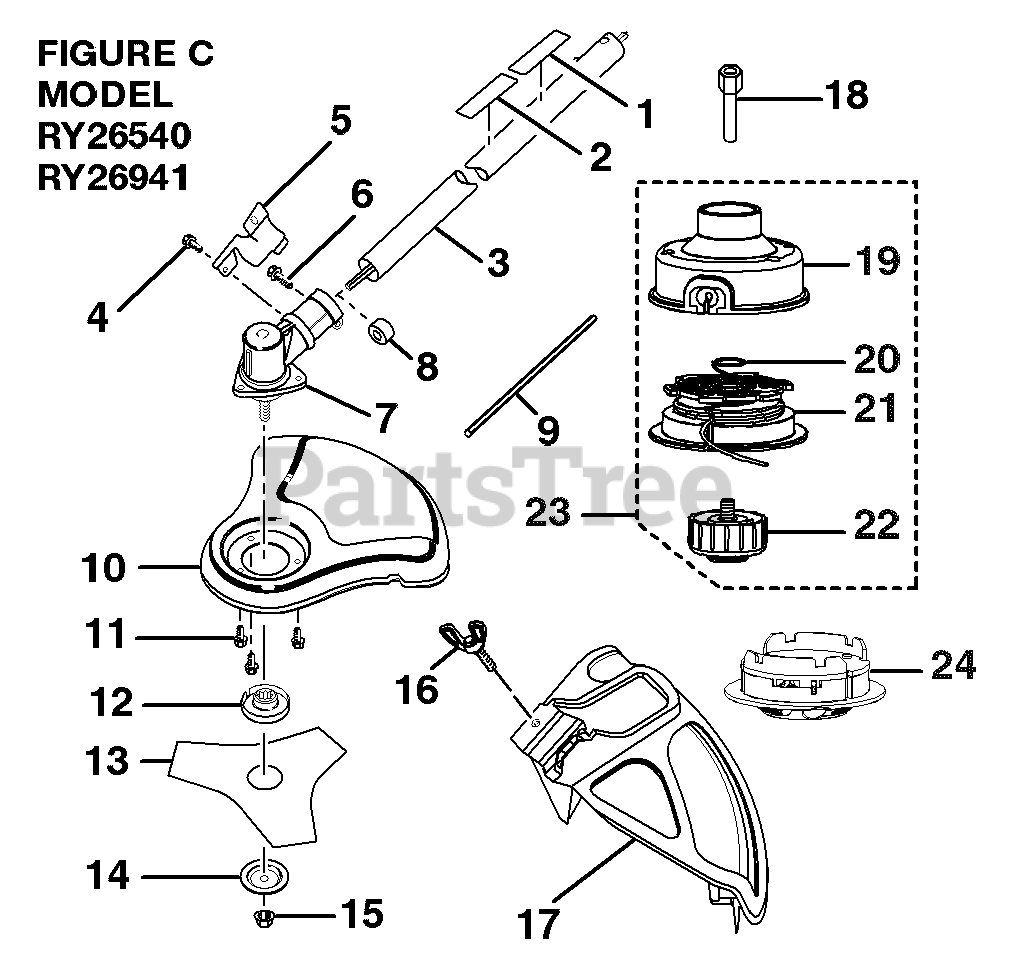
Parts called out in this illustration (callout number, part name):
1	Expand-it Label
2	Brushcutter Safety Label
3	Straight Shaft Assembly
4	Screw (10-24 x 5/8 in.)
5	Clamp
6	Screw (1/4-20 x 1-1/4 in.)
7	Gear Head
9	Gear Head Locking Tool
10	Brushcutter Guard
11	Screw (10-24 x 1/2 in.)
12	Flanged Washer
14	Cupped Washer
15	Blade Nut
16	Screw (1/4-20 x 1-1/4 in.)
17	Grass Defector Assembly
19	Bump Feed String Head
20	Spring
21	Bump Feed Spool
22	Spool Retainer
23	Bump Feed String Head Assembly
24	Dual Spool™ Fixed Line String Head Insert
